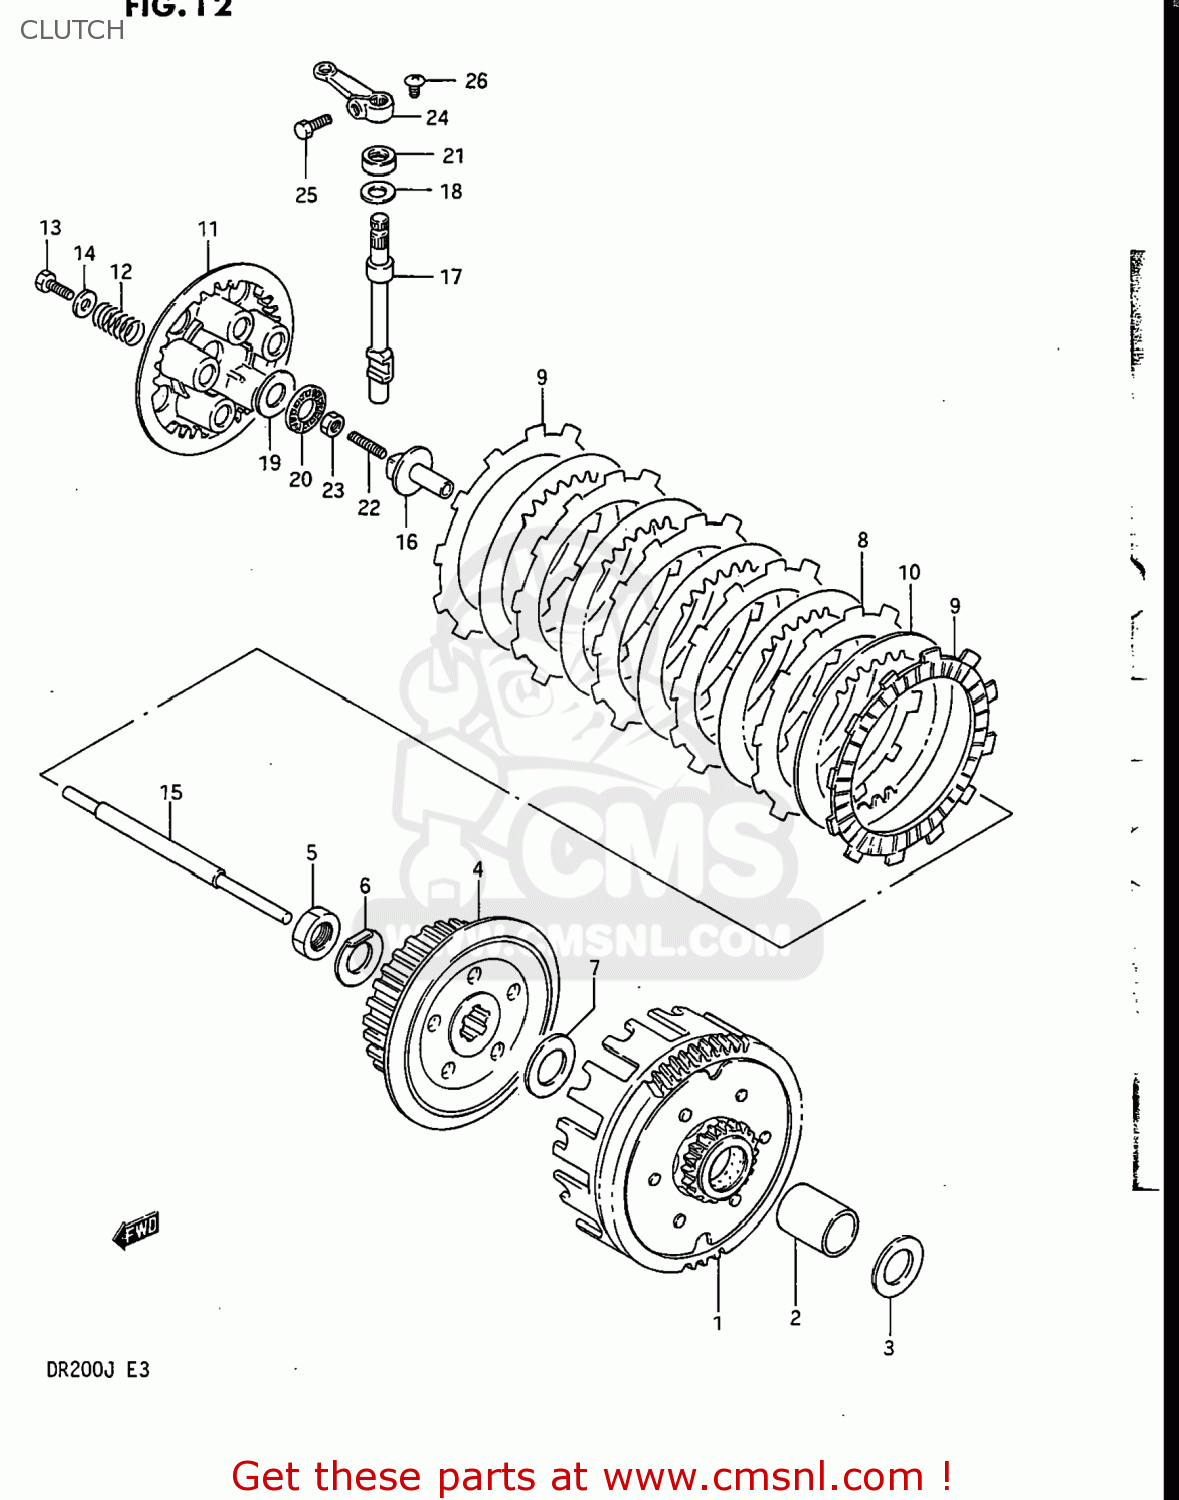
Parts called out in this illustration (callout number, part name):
1	GEAR ASSEMBLY,PRIMARY DRIVE
2	SPACER
3	WASHER
4	HUB,CLUTCH SLEEVE
5	NUT
6	WASHER
7	WASHER
8	PLATE,CLUTCH DRIVE (MCA)
9	PLATE,CLUTCH DRIVE (NAS)
10	PLATE,CLUTCH DRIVEN (NAS)
11	PLATE,CLUTCH PRESSURE
12	SPRING
13	BOLT(5X16)
14	WASHER (5.5X16X1.2)
15	ROD,CLUTCH PUSH
16	PIECE,CLUTCH PUSH
17	CAMSHAFT,CLUTCH RELEASE
18	WASHER,THRUST
19	WASHER
20	BEARING(15X28X2)
21	OIL SEAL
22	SCREW(6X25)
23	NUT 6MM
24	ARM,CLUTCH RELEASE
25	BOLT
26	SCREW
